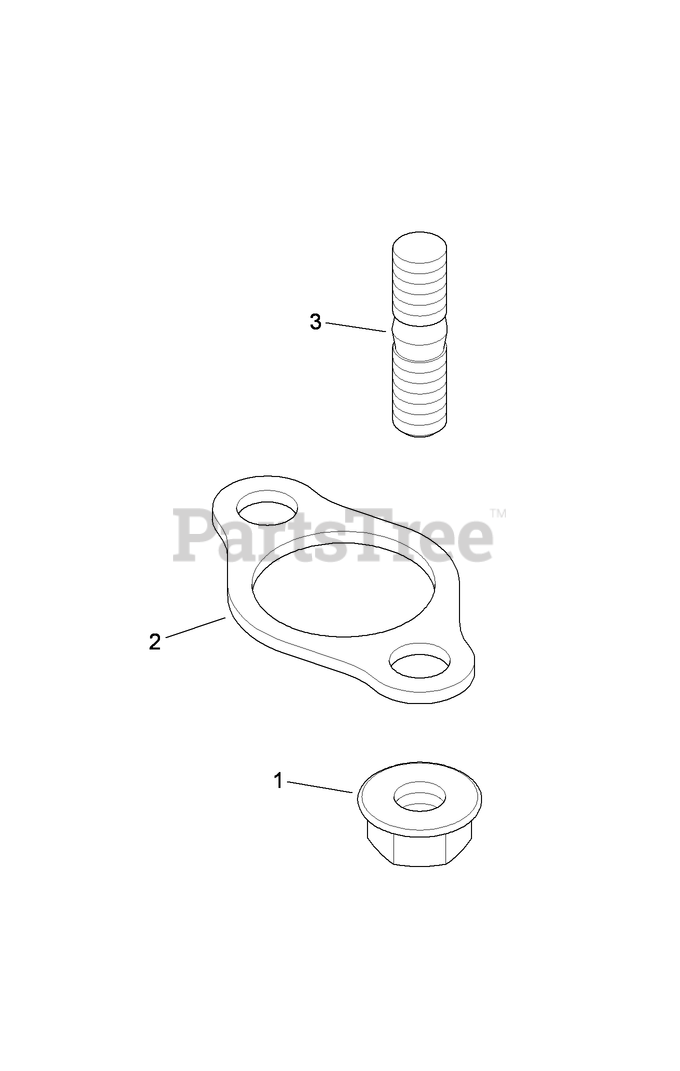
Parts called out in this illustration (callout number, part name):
1	NUT-FLANGE (M8X1.25)
2	GASKET-EXHAUST
3	STUD (M8X1.25X33)
